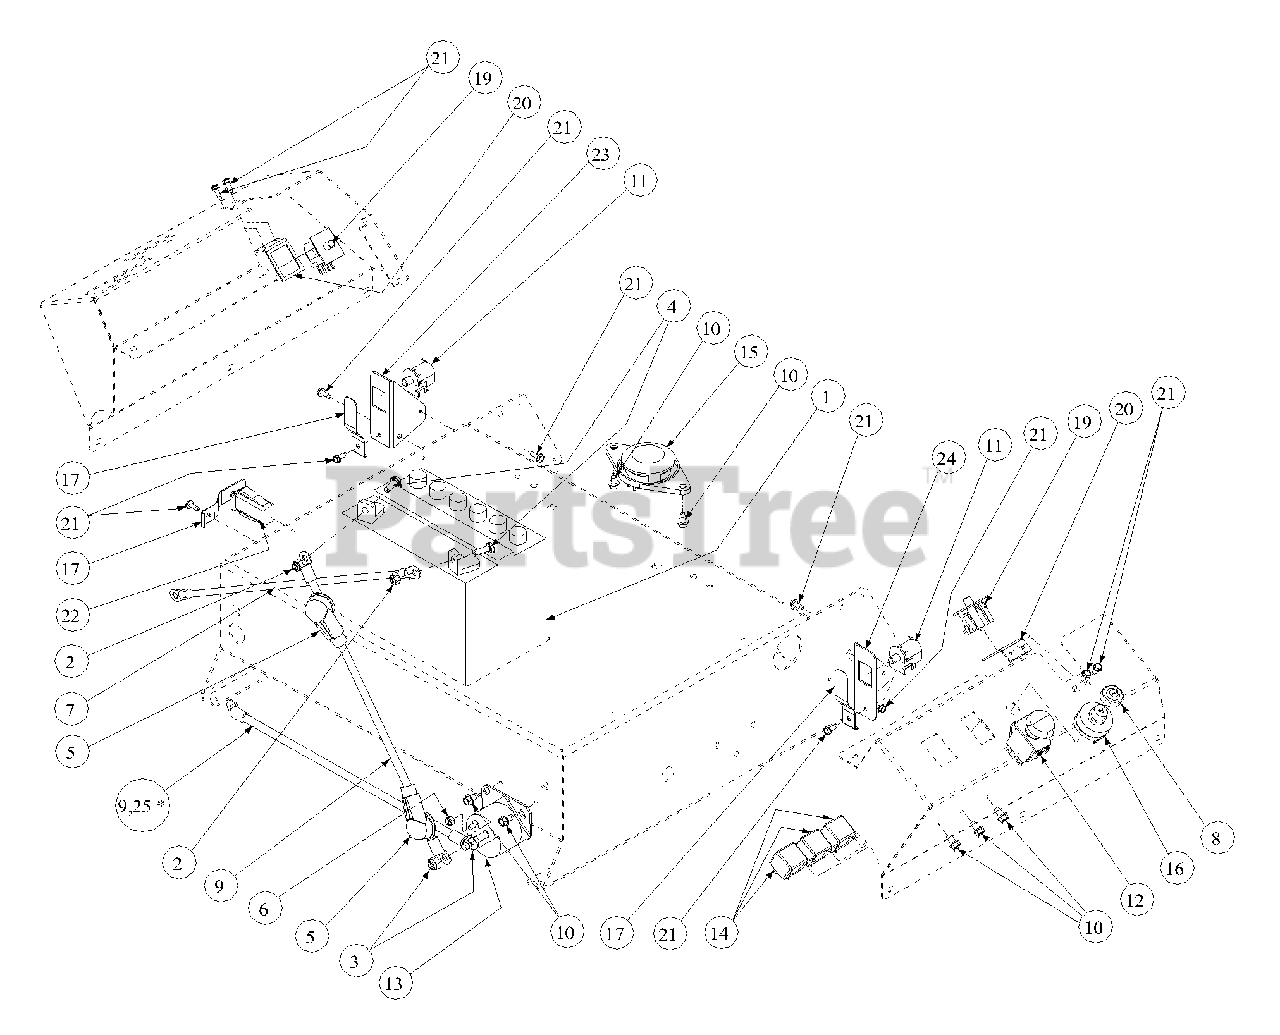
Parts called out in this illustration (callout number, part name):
1	Battery, 12V 260CCA 30Min
2	Lock Nut, Nylon Insert, 1/4-20
3	Nut, 5/16-18, Nylock
4	Hex Cap Screw, 1/4-20 x .75
5	Boot, 1" OD Rubber Battery-PST Red
6	Lock Nut, Nylon Insert, 10-32
7	Cable, Battery, Black, 17"
8	Nut, 5/8-32, w/Cap
9	Cable, Battery, Red, 15" (Kawasaki)
10	Self Tapping Screw, 1/4-20 x 1/2
11	Normally Closed Safety Switch
12	Electric PTO Switch
13	Solenoid
14	Relay, 12V 40A
15	Normally Closed Seat Switch
16	Switch, Ignition, 6 Pin
17	Safety Switch Retainer Spring
19	Neutral Switch
20	Neutral Switch Mounting Bracket
21	Self Tapping Screw, 10-32 x 1/2
22	Switch, Plunger
23	Bracket, Safety Switch, Left Hand
24	Bracket, Safety Switch, Right Hand
25	Cable, Battery, Red, 24" (Briggs)
